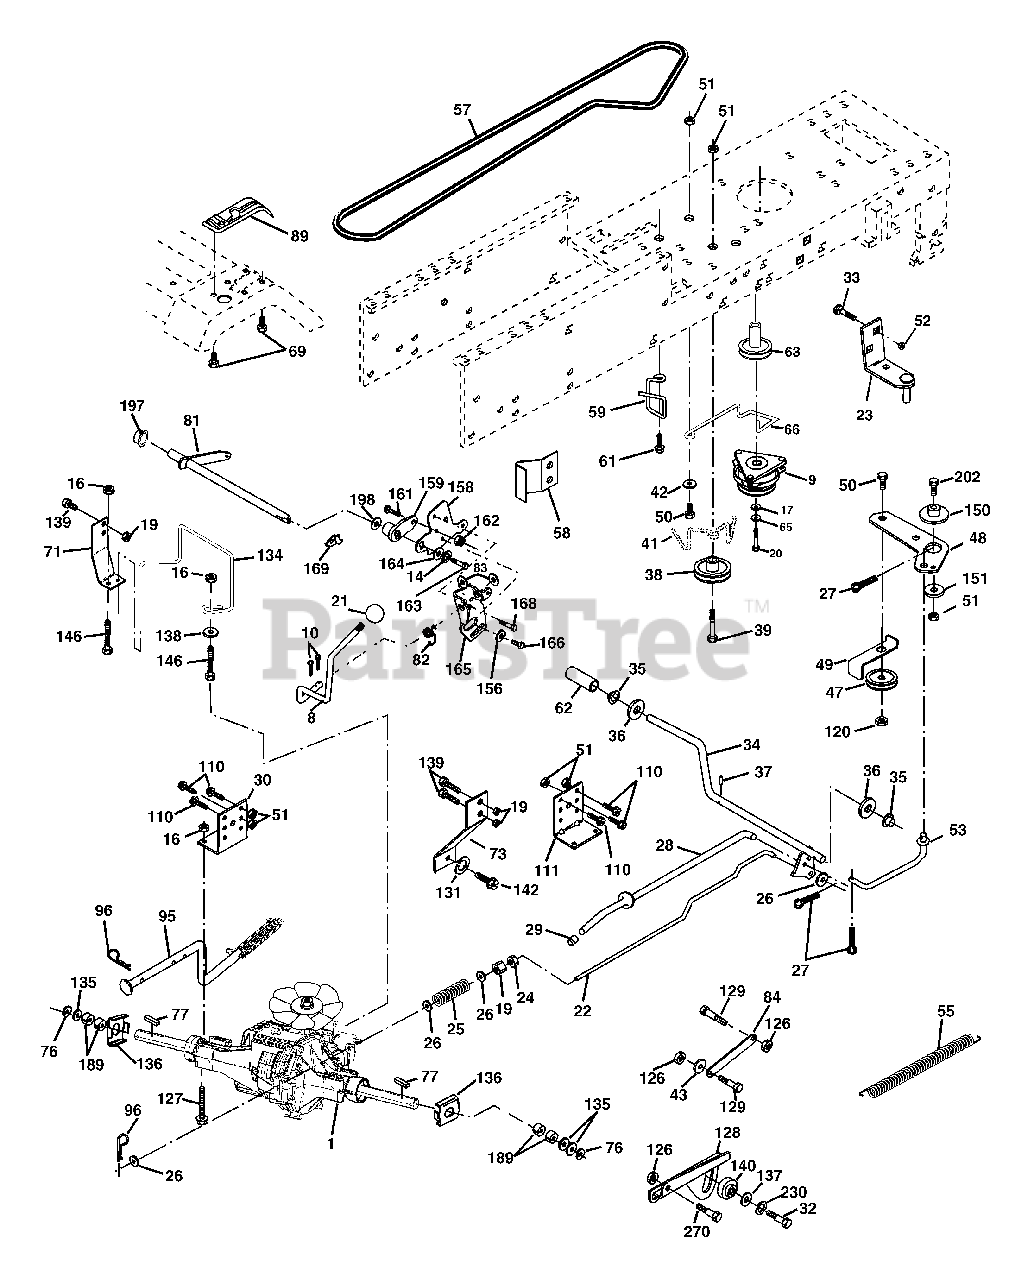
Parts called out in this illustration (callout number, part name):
8	Rod Shift Fender Adjust Yt
9	Clutch Ogura
10	Pin, Cotter 1/8 x 1
14	Washer Lock Hvy Helical
16	Nut Lock Hx w/Ins. 5/16-18 Unc
17	Washer 1-1/2 x 15/32 x .250
19	Nut, Lock Hex w/Ins. 3/8-16 Unc
20	Bolt 7/16-20 x 4 Gr. 5-1.5
21	Knob
22	Rod, Brake
23	Bracket Anti Rotation
24	Nut, Hex Jam 3/8-16
25	Spring, Rod, Brake
26	Washer 13/32 x 13/16 x 16 Ga.
27	Pin, Cotter 1/8 x 3/4
28	Rod, Brake, Park
29	Cap, Brake Parking Black
30	Bracket, Transaxle, L.H.
32	Bolt 5/16-18 Unc x 3/4
33	Bolt 3/8-16 x 1
34	Shaft, Foot Pedal
35	Bearing Nylon
36	Washer 21/32 x 1 x 16 Gauge
37	Pin,Roll 3/16 x 1
38	Pulley Idler Composite
39	Bolt Rdhd 3/8-16 Unc x 3
41	Keeper, Idler
42	Washer 13/32 x 13/16 x 12 Ga.
43	Bolt Shoulder 5/16-18 Unc
47	Pulley, Idler
48	Bellcrank Clutch Grnd Drv Stl
49	Retainer, Belt
50	Bolt 3/8-16 x 1-1/2
51	Nut, Crownlock 3/8-16
52	Nut
53	Link, Clutch
55	Spring, Return, Clutch
57	V-Belt, Drive
58	Keeper, Belt, Transaxle, R.H.
59	Keeper Belt Centerspan
61	Screw 3/8-16 x .875
62	Cover, Foot Pedal
63	Pulley, Engine
65	Washer, Lock Hvy Hlcl Spr 7/16
66	Keeper Belt Engine F-proof
69	Screw Hex Wsh Hi-Lo 1/4-1/2 Unc
71	Strap Torque Lh Hydro-3000
73	Strap Torque Rh Hydro-3000
76	E-Ring
77	Key Square 1/4 x 2
81	Shaft Asm Cross Tapered
82	Spring, Torsion
83	Washer 17/32 x 3/4 x 16 Gauge
84	Link Transaxle
89	Console
95	Control Asm Bypass Hydro-3000
96	Retainer Spring 1" Zinc/cad.
110	Bolt Hex 3/8-16 x 3/4 Gr. 5
111	Bracket, Transaxle, R.H.
120	Nut Lock Flg. 3/8-16 Unc
126	Nut Lock 5/16-18 Nc Thd
127	Bolt Hex Flghd 5/16-18 x 3.0 Gr. 5
128	Lever Control HG 3000
129	Bolt Shoulder 5/16-18 Unc
131	Washer Lock 5/16
134	Rod Actuator Bypass Hydro-3000
135	Washer 1-1/32 x 1-5/8 x 16 Ga.
136	Washer Axle Flange
137	Washer 11/32 x 3/4 x 12 Ga.
138	Washer 11/32 x 1.25 x 16 Ga.
139	Bolt Fin Hex 3/8-16 x 3/4
140	Bushing Pinion Sector
142	Bolt 5/16 x 24 x 1
146	Bolt Hex Flghd 5/16-18 x 2-1/4
150	Spacer
151	Washer 13/32 x 2 x 10 Ga.
156	Washer Srrted 5/16ID x 1.125
158	Bracket Shift Mount
159	Hub Shift
161	Bolt Rdhd Sqnk 1/4-20 x 3/4 Gr 5
162	Nut Crownlock 1/4-20 Unc
163	Bolt Hex Fin 1/4-20 Unc x 1 Gr 5
164	Washer 5/8 x .281 x 10 Ga
165	Bracket Pivot Lever
166	Screw 5/16-18 x 5/8
168	Bolt Shoulder 5/16-18 x .561
169	Plate Fastening Lt
189	Washer Spacer Axle
197	Nyliner Snap-In 5/8" Id
198	Washer Nyl 7/8 Id x .105
202	Bolt Carr Sh 3/8-16 x 1-3/4 Gr.5
230	Washer Lock 5/16
270	Bolt 5/16-18 x 5/8 Gr. 5
